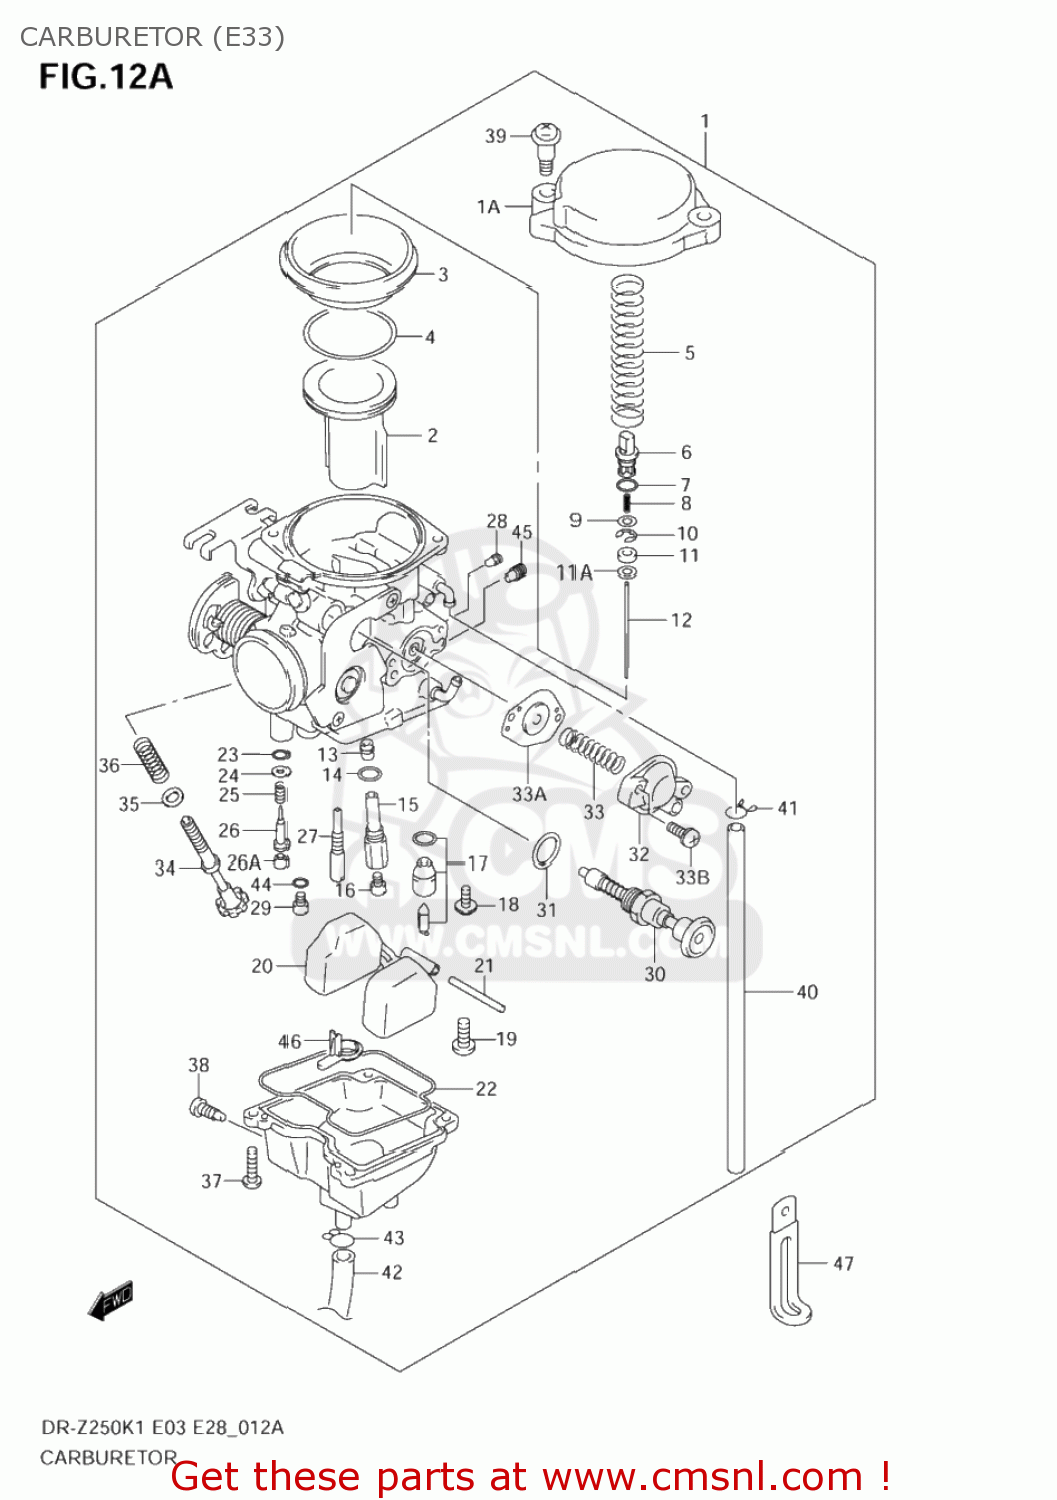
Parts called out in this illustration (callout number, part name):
1	CARBURETOR ASSY
1A	COVER,DIAPHRAGM
2	VALVE,PISTON
3	DIAPHRAGM
4	RING
5	SPRING
6	HOLDER
7	O RING(D:1.9,ID:4.8)
8	SPRING
9	WASHER
10	E RING,MULTIPLE JET NOZZLE
11	RING
11A	WASHER
12	NEEDLE JET
13	JET
14	O RING
15	HOLDER,JET
16	JET,MAIN (132.5)
17	VALVE ASSY,NEEDLE
18	SCREW
19	SCREW
20	FLOAT ASSY
21	PIN,FLOAT
22	GASKET (NAS)
23	O RING,PILOT AIR SCREW
24	WASHER
25	SPRING,THROTTLE SCREW
26	ADJUSTER
26A	PLUG
27	JET,PILOT(12.5)
28	JET(80)
29	JET,MAIN(55)
30	PLUNGER ASSY
31	O RING
32	COVER ASSY
33	SPRING
33A	DIAPHRAGM ASSY
33B	SCREW
34	ADJUSTER
35	PACKING (NAS)
36	SPRING
37	SCREW
38	SCREW,DRAIN
39	SCREW
40	HOSE
41	CLIP
42	HOSE(4.5X8X650)
43	CLIP
44	O RING
45	JET,POWER(150)
46	RING
47	CLAMP(L:65)
